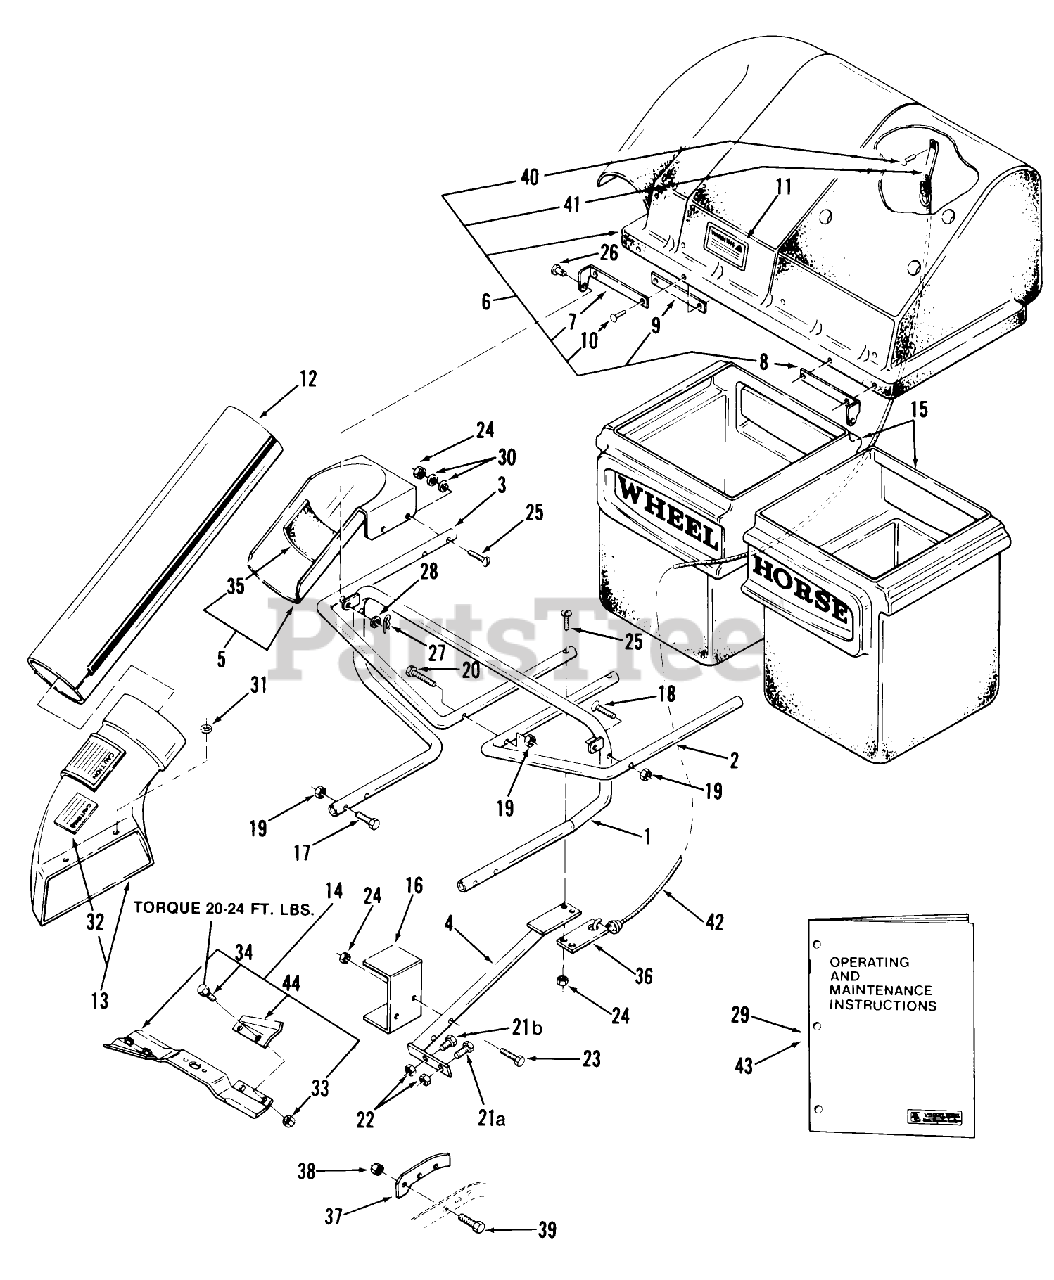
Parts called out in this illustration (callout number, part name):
1	Main Frame
2	SUPPORT-LEFT TUBE
3	Support Tube R. H.
4	Brace Tube
5	SUPPORT-COLLECTOR TB
6	Collector Top Assy.
7	Hinge R.H.
8	Hinge L.H.
9	BACKING PLATE
10	Poprivet 5/32 x 1/2 Long
11	Warning Decal
12	Tube
13	ASSY-ELBOW
14	High Lift Blade
15	CAN-CLIPPINGS
16	Muffler Shield (8 HP Engine Only)
17	Bolt
18	Screw Flat Hd. Mach. 5/16 x 2 1/2
19	Nut
20	HHCS
22	Nut
23	Bolt 1/4-20 X 1 1/2
24	Nut
25	Srew Flat Hd. Mach. 1/4-20 x 1 1/4
25	Screw Flat Hd. Mach. 1/4-20 x 1 1/2
26	PIN
27	Hairpin Cotter
28	Washer
29	Operating and Maintenance Instructions
30	WASHER
31	Collar
32	DECAL-CAUTION
33	NUT-LOCK 5/16-18
34	BOLT 5/16-18X5/8
36	SUPPORT
37	Plate
38	Nut
39	Bolt
40	POPRIVET
41	Bracket
42	Strap
43	Supplemental Instruction Sheet
44	Lift Tab Kit
